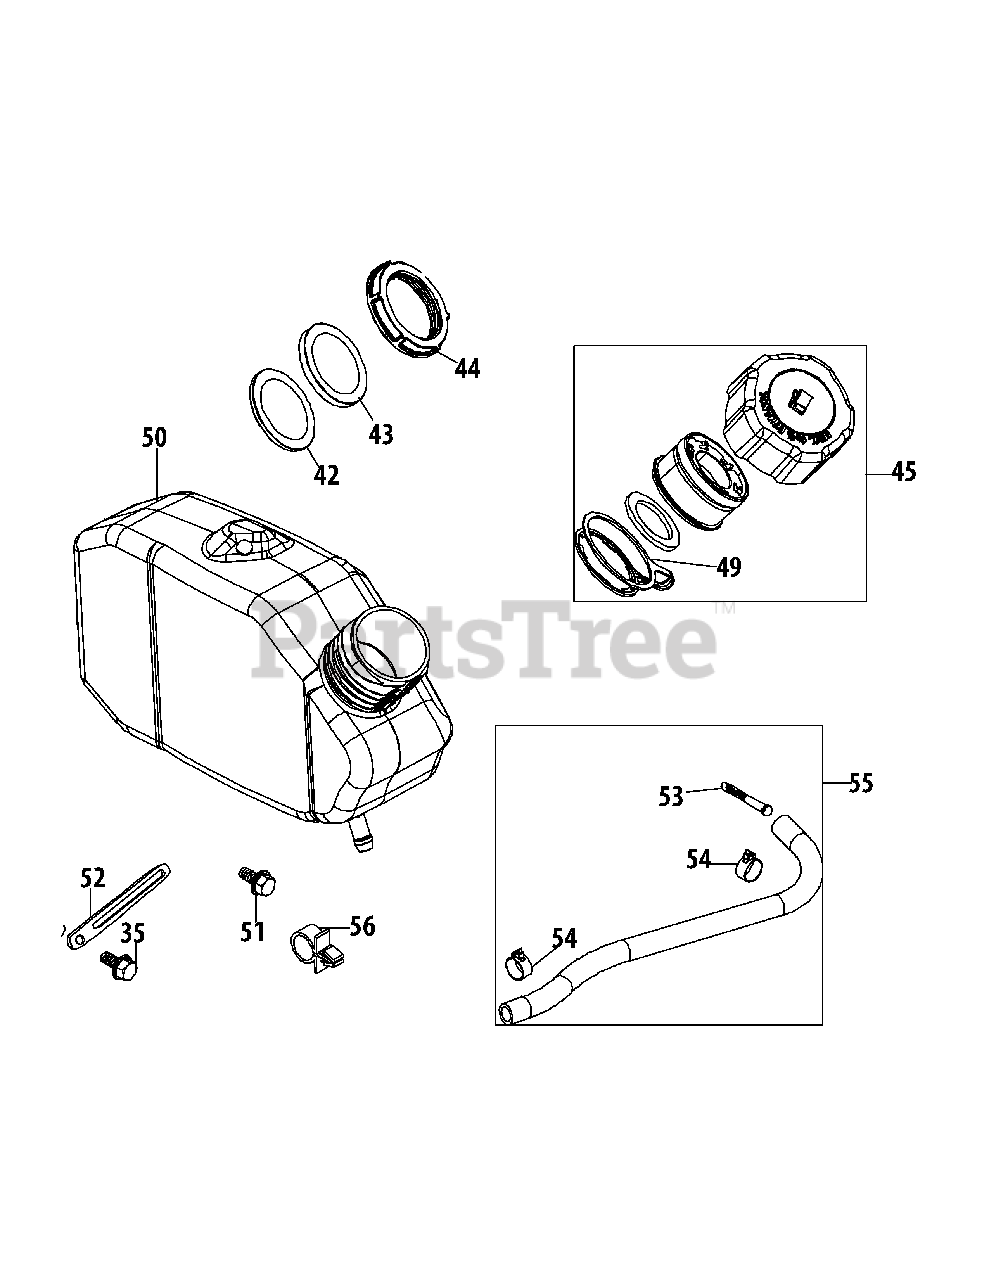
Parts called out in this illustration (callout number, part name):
35	BOLT M6-1 x 14 GR8.8
42	FUEL TANK LOWER GROMMET
43	FUEL TANK UPPER GROMMET
44	FUEL TANK NUT
45	FUEL CAP ASSEMBLY
49	FUEL CAP TETHER
51	BOLT M6-1 x 12 GR8.8
52	FLEXIBLE CLAMP
53	FUEL FILTER
54	HOSE CLAMP
55	FUEL LINE
56	FUEL LINE SUPPORT CLAMP
